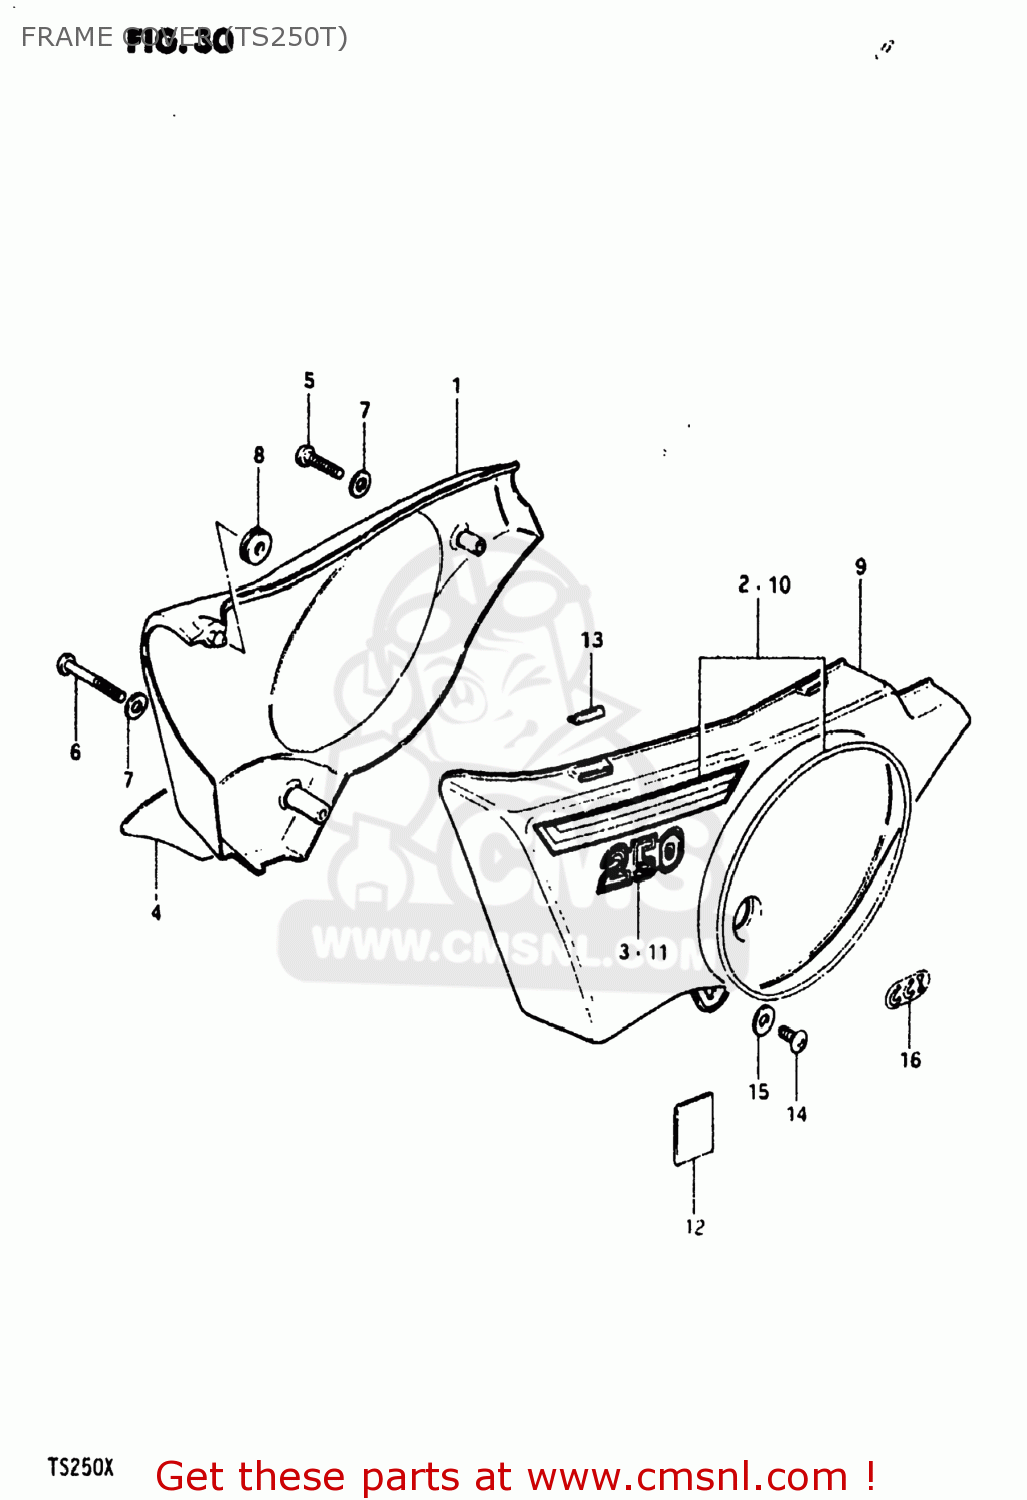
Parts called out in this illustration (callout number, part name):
1	COVER,FRAME,RIGHT
2	TAPE SET,FRAME COVER
3	EMBLEM
4	EMBLEM,FRAME COVER,RIGHT
5	SCREW
6	SCREW
7	WASHER
8	CUSHION
9	COVER,FRAME,LEFT
10	TAPE SET,FRAME COVER
11	EMBLEM
12	PROTECTOR(170X95X3.0)
13	CUSHION,FRAME COVER
14	SCREW 6X12
15	WASHER
16	EMBLEM,CCIS
